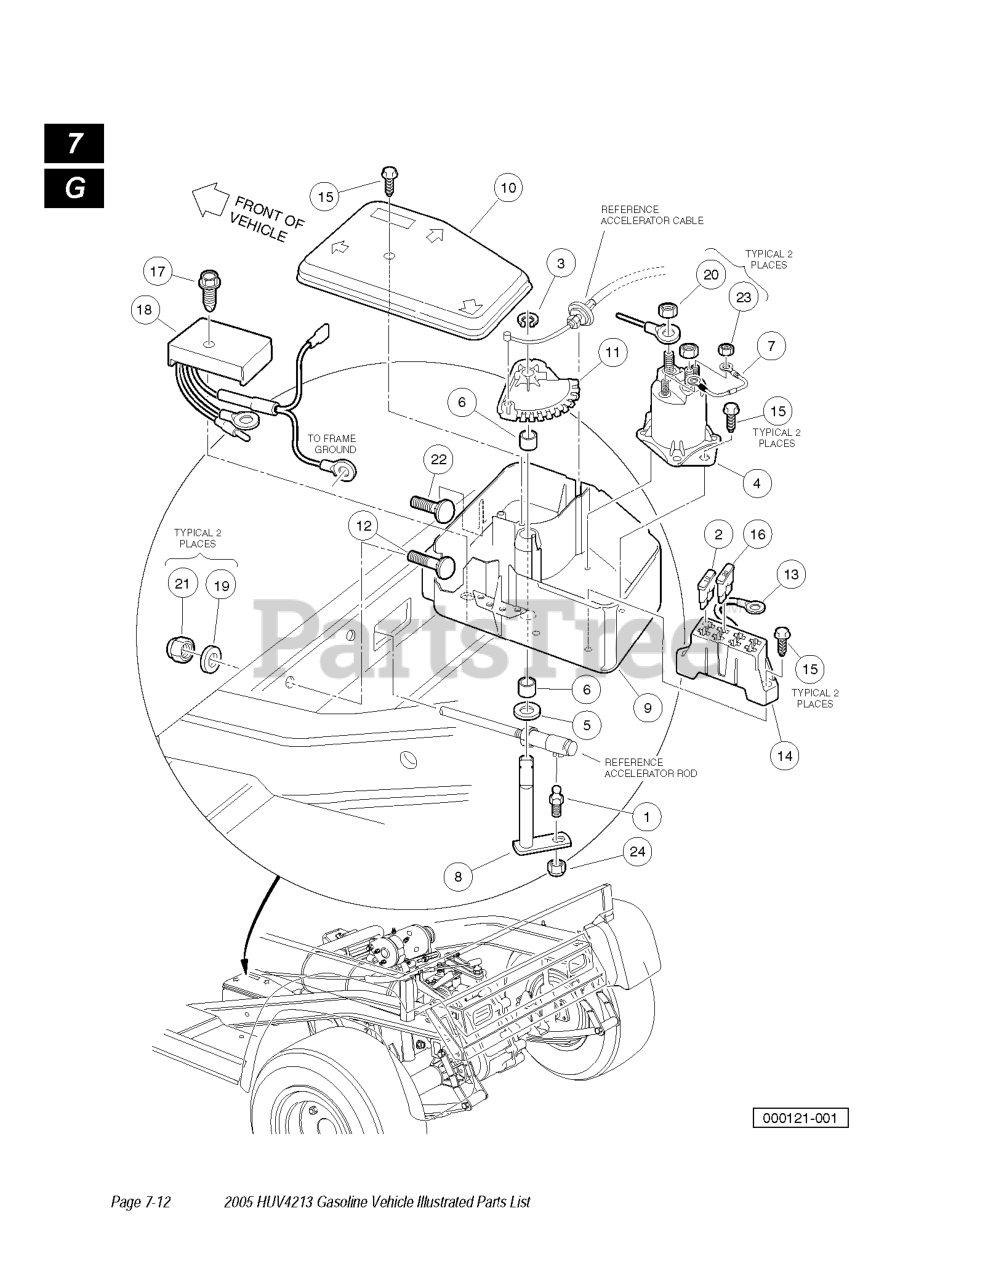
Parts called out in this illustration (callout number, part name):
2	10 AMP FUSE
4	SOLENOID, 12 VOLT
6	BUSHING, SECONDARY WGHT SPLIT
7	ASM, DIODE
8	BELL CRANK AND SHAFT ASSY
9	BOX, ELECTRICAL COMPONENT
10	COVER, OHV ELECTRIC BOX
11	CAM, ELECTRIC BOX
12	BOLT,5/16-18 X 2.0 RD HD SQ NK
13	WIRE ASSY, #10 RED
14	FUSE BLOCK
15	SCREW, #12-16 X .625 HI-LO
16	FUSE - 20 AMP
17	SCREW, 1/4-15 X .50 HI-LO HEX
18	ASM, VOLTAGE REGULATOR
19	WASHER, 5/16 TYPE A FLAT
20	NUT, 5/16-18 HEX
21	LOCKNUT, 5/16-18 NYLON INSERT
22	BOLT 5/16-18 X 1.5
23	NUT, #10-32 HEX
24	LOCKNUT, 1/4-28 NYLON INSERT
